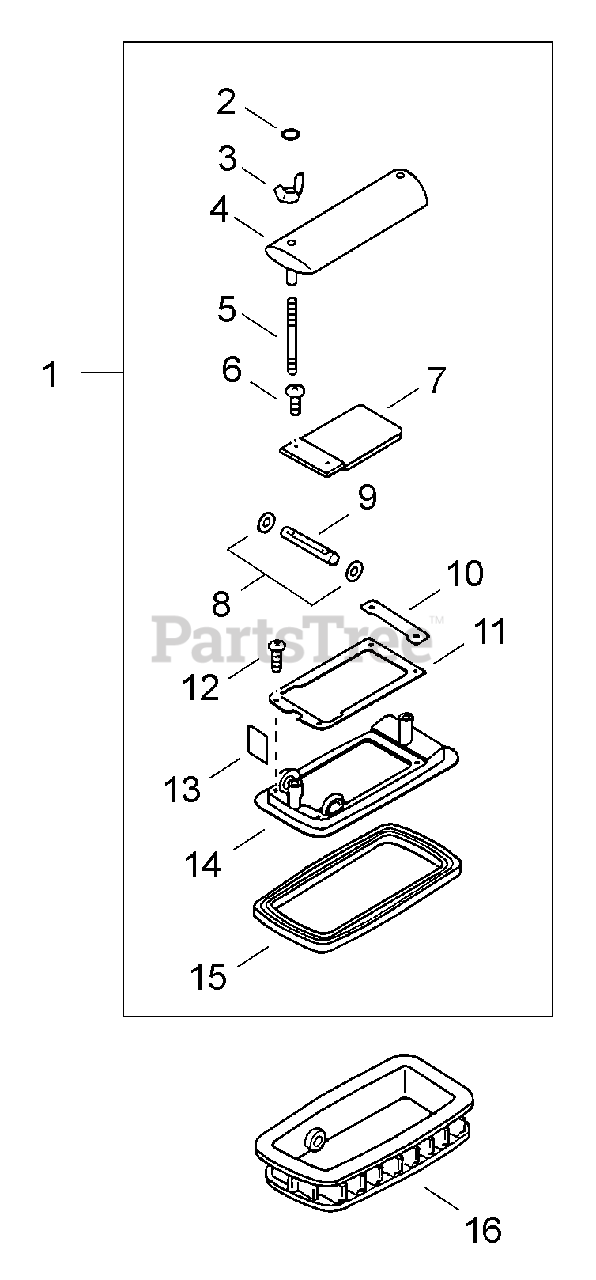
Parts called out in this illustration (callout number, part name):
1	SHUTTER ASSY
2	O-RING - 4
3	WINGNUT - 5
4	STABILIZER
5	STUD - 5X50
6	SCREW - 4X10
9	SHAFT, SHUTTER
11	SHUTTER, RATE CONTROL
12	SCREW - 4X14
14	MOUNT, SHUTTER
15	GASKET
16	ADAPTOR, DUST OUTLET
